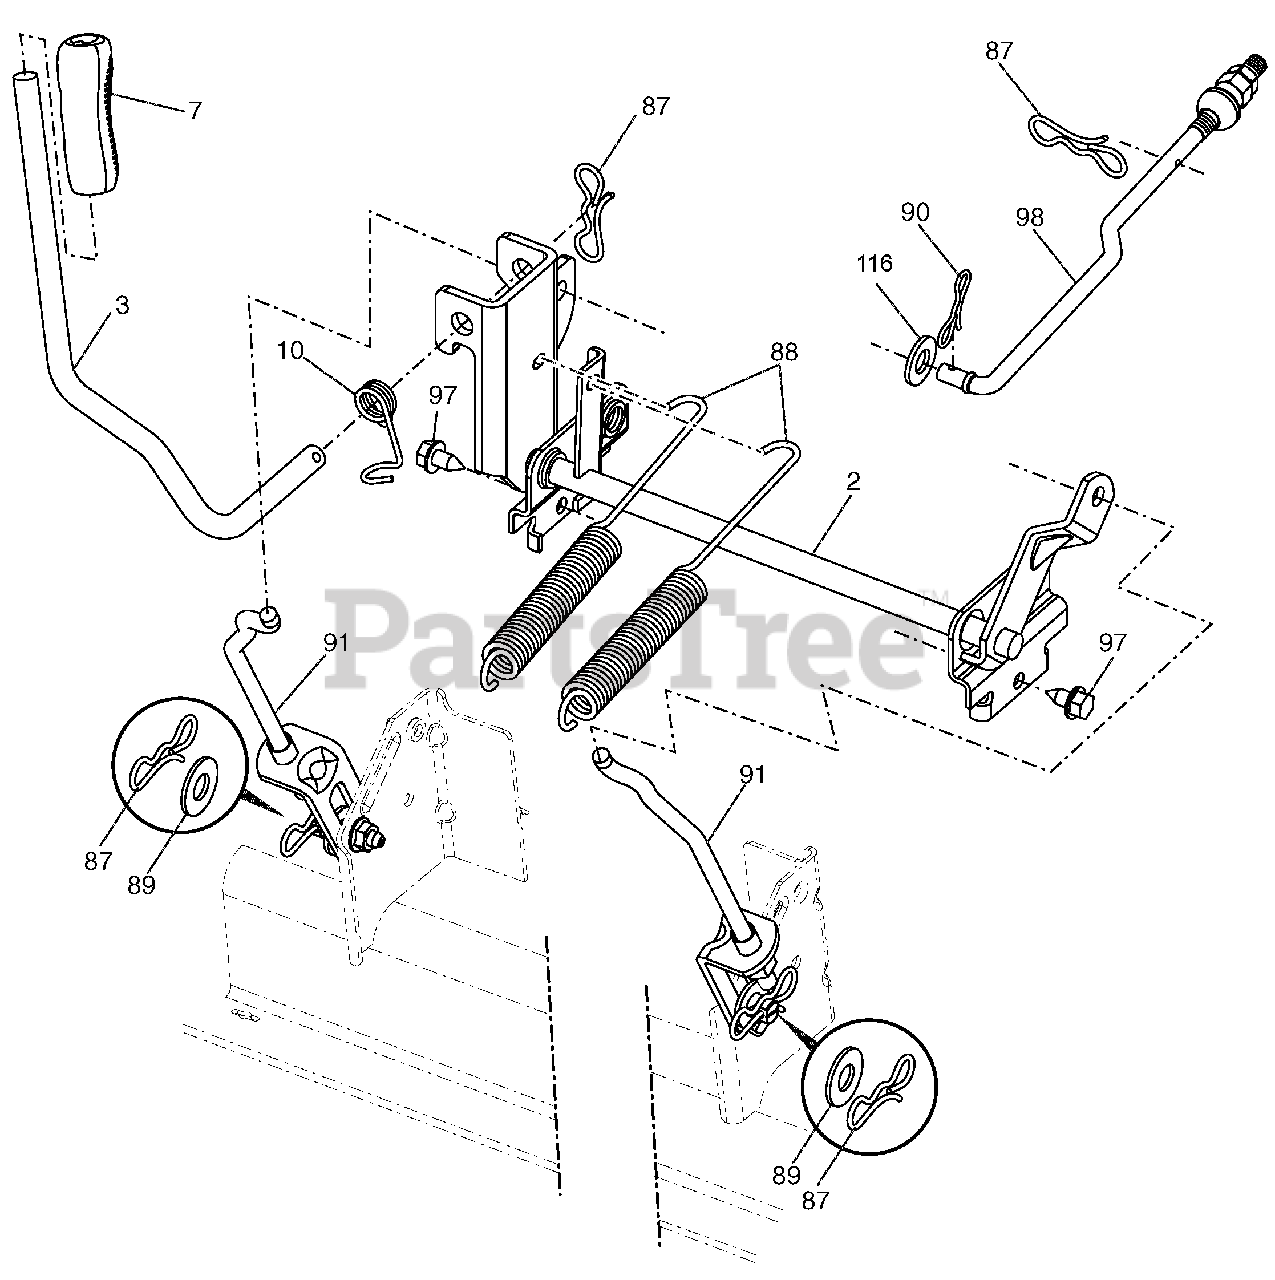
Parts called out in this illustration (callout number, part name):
2	SHAFT ASM., LIFT
3	LEVER.LIFT.HANDLE.LT
7	GRIP LEVER 5625 LD BLACK 428
10	SPRING.TORSION.HANDLE.LIFT
87	PIN.COTTER.7/16.BOW TIE LOCK
88	SPRING.LIFT ASSIST
89	WASHER.CLEAR ZINC
90	PIN.COTTER.5/16.BOW TIE LOCK
91	LINK ASM.LIFT.54"TG
97	SCREW.HEXWSH THDR3/8-16X3/4.BL
98	LINK ASM.SUSP.FRONT.MWR.10.5
116	WASHER 15/32 X 15/16 X 16 GA.
